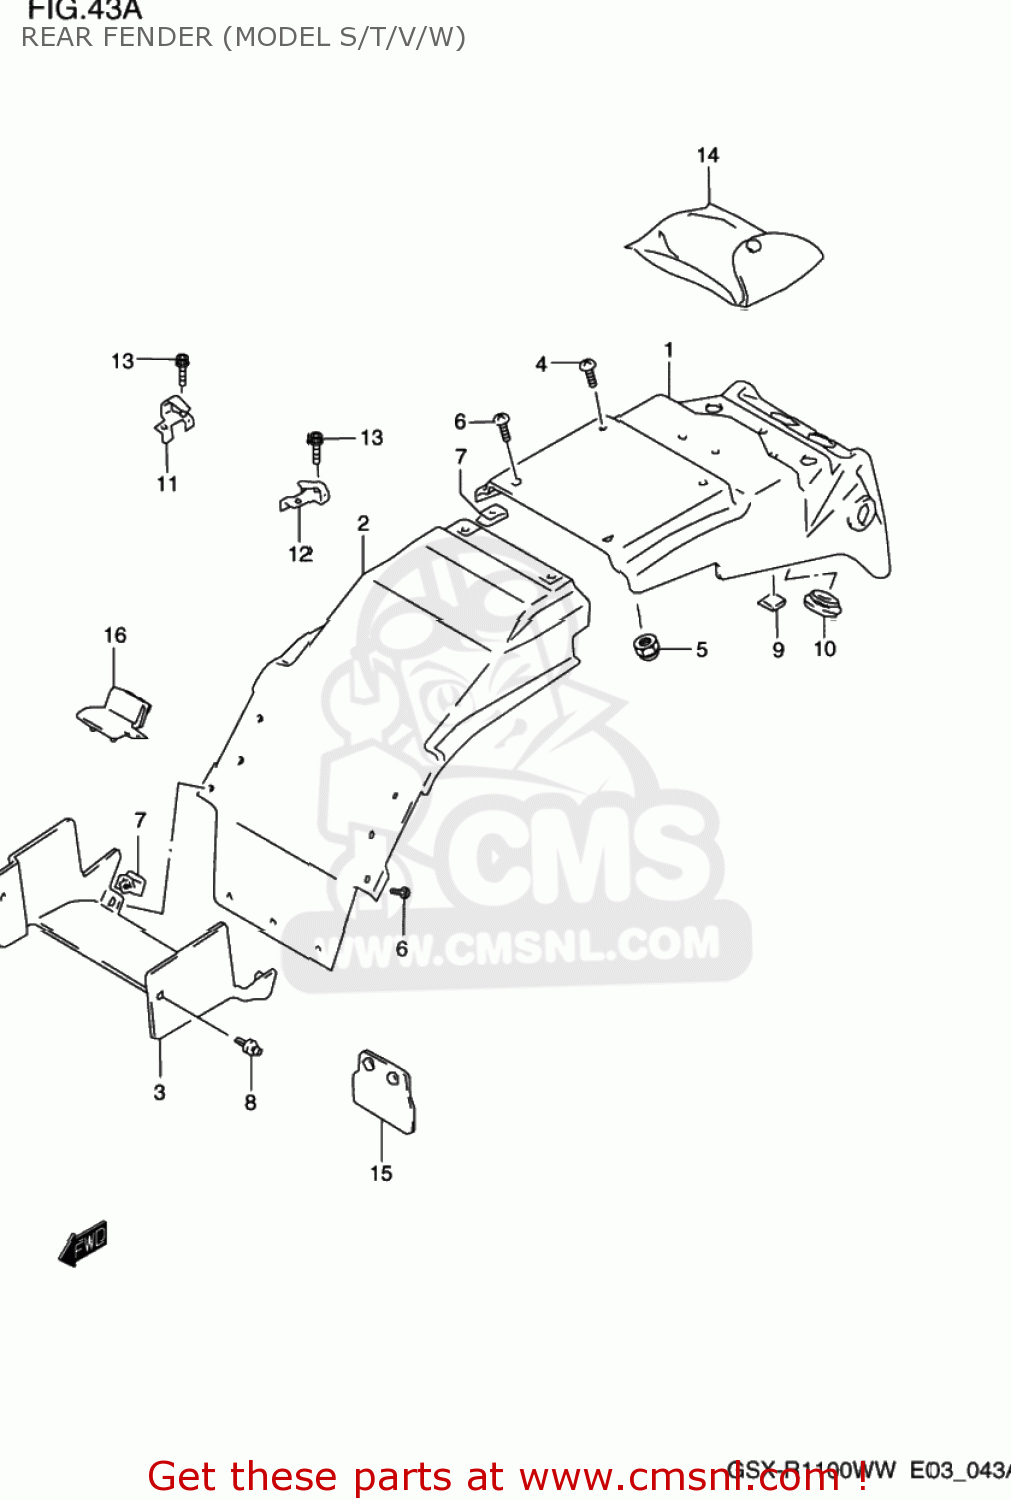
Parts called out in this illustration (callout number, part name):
1	FENDER,RR UPR
2	BODY,RR FENDER UPR FR NO2
3	FENDER,RR UPR FR NO.1
4	SCREW
5	NUT
6	SCREW 5X12
7	NUT,HEADLAMP HOUSING,UPPER
8	CLIP(BLACK)
9	TAPE,REAR COMBINATION LAMP HOLE
10	CAP
11	HOLDER,HELMET,R
12	HOLDER,HELMET,L
13	BOLT
14	TOOL ASSY
15	GUIDE,RR FENDER MUD
16	MUD GUARD,REAR FENDER
